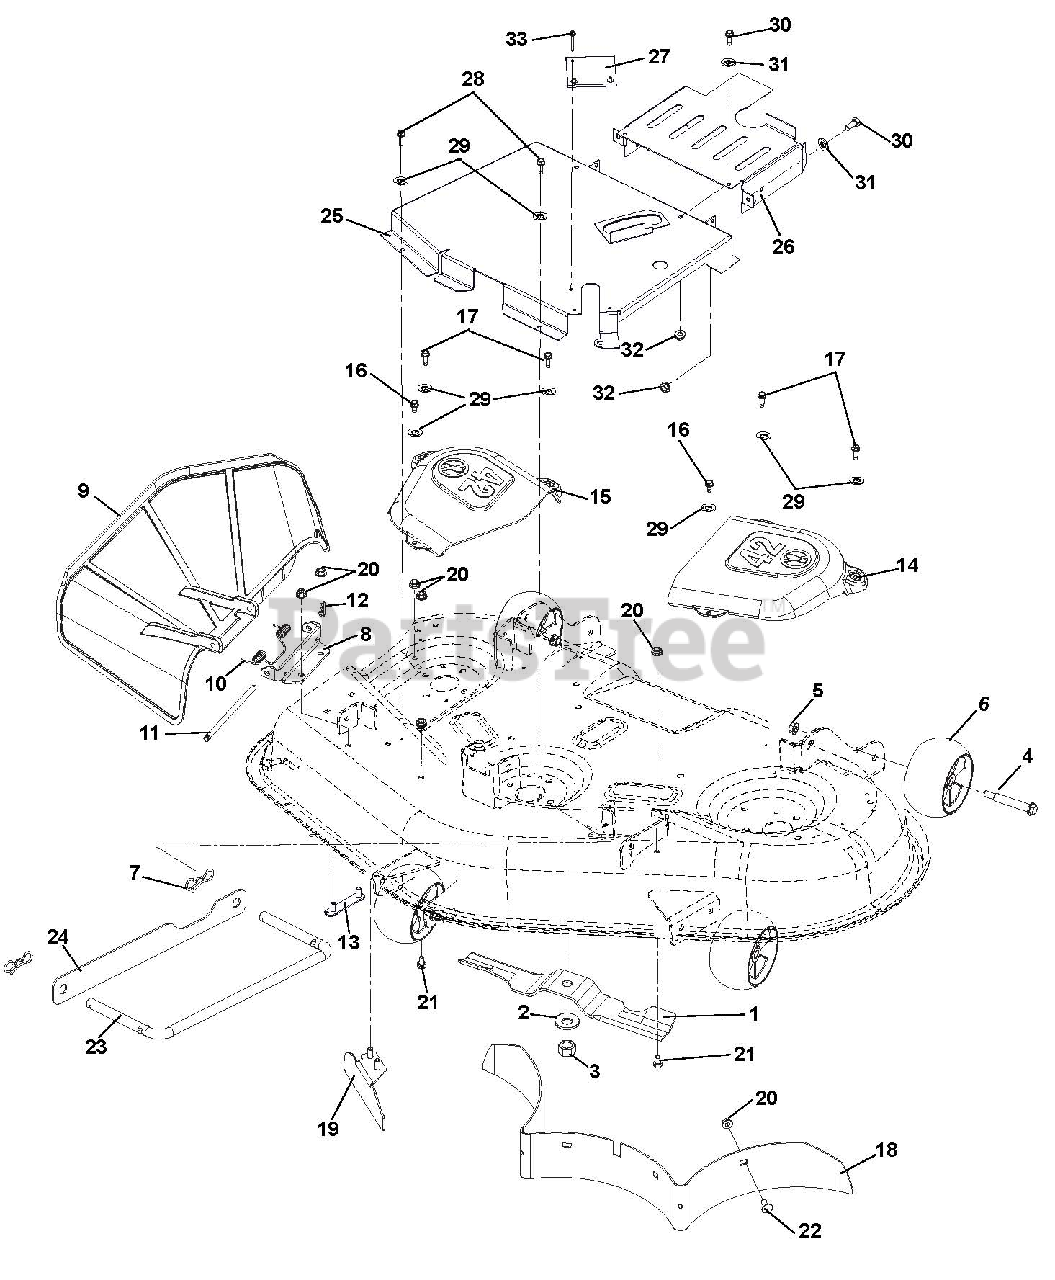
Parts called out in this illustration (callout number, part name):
1	BLADE, MOWER 14.83 (.188 THK)
2	WSHR-BLVL .669X1.535X.138
3	NUT-HEX .62-18 YWZC
4	BLT-SHLDR .38-16X2.50 HWH G5
5	@NUT-LK-TOP-FLG .38-16 YWZC
6	ANTI-SCALP WHEEL - 5X OS
7	PIN,BOW TIE LOCKING .091X1.875
8	BRKT-DISCHARGE CHUTE MOUNT 42"
9	CHUTE, DISCHARGE - MOLDED
10	SPRING-TORSION
11	PIN, 5/16 X 5.80"
12	PIN-HAIR INT .08X.18X1.18 YWZC
13	WMT-DISCHARGE CHUTE MT. STRAP
14	BELT COVER - LH 42"
15	BELT COVER - RH 42"
16	SCR-TAP .25-20X.50 HWH TR YWZ
17	SCR-TAP .25-20X.75 HWH TR YWZ
18	BAFFLE, REAR (42)
19	WLDMT-BAFFLE, DISCHARGE 42"
20	@NUT-LK-TOP-FLG .31-18 YWZC
21	@BLT-HEX .31-18X.50 GR5 YWZC
22	@BLT-RHDSSQNK .31-18X.75 G5YZ
23	WIREFORM, DRAG LINK
24	STRAP, DRAG LINK
25	GUARD, 42" ZOOM/ZT CE BELT
26	COVER, REAR DECK BELT
27	GUARD, RUBBER DECK SPRING
28	SCR-TAP .25-20X.50 LGHWH TR YZ
29	NUT-PUSH .25X.50 O.D.
30	@BLT-HEX .25-20X.50 GR5 YWZC
31	@WSHR-FL-STL.281X.62X.065 YWZC
32	@NUT-LK-TOP-FLG .25-20 YWZC
33	RVT-POP .187X.402 DOME ST
